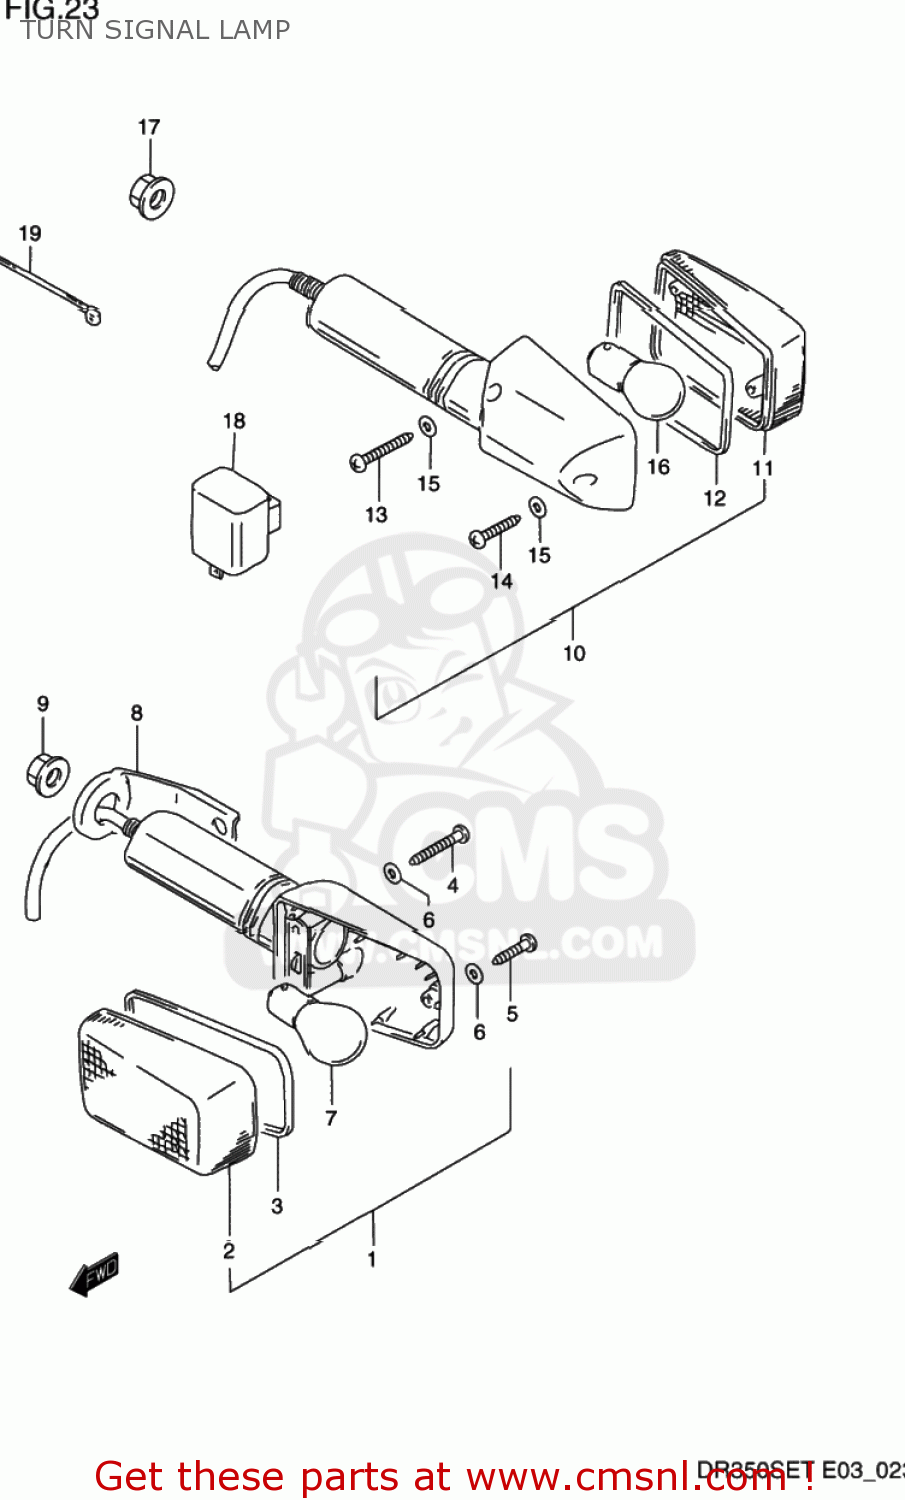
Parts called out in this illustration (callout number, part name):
1	LAMP ASSY,FR TURN SIGNAL
2	LENS
3	GASKET (NAS)
4	SCREW(3X30)
5	SCREW
6	GASKET (NAS)
7	BULB(12V21W)
8	BRACKET,FRONT TURN SIGNAL
9	NUT
10	LAMP ASSEMBLY,REAR TURN SIGNAL
11	LENS
12	GASKET (NAS)
13	SCREW(3X30)
14	SCREW
15	GASKET (NAS)
16	BULB(12V21W)
17	NUT
18	RELAY ASSY,TURNSIGNAL
19	CLAMP(L:33)
